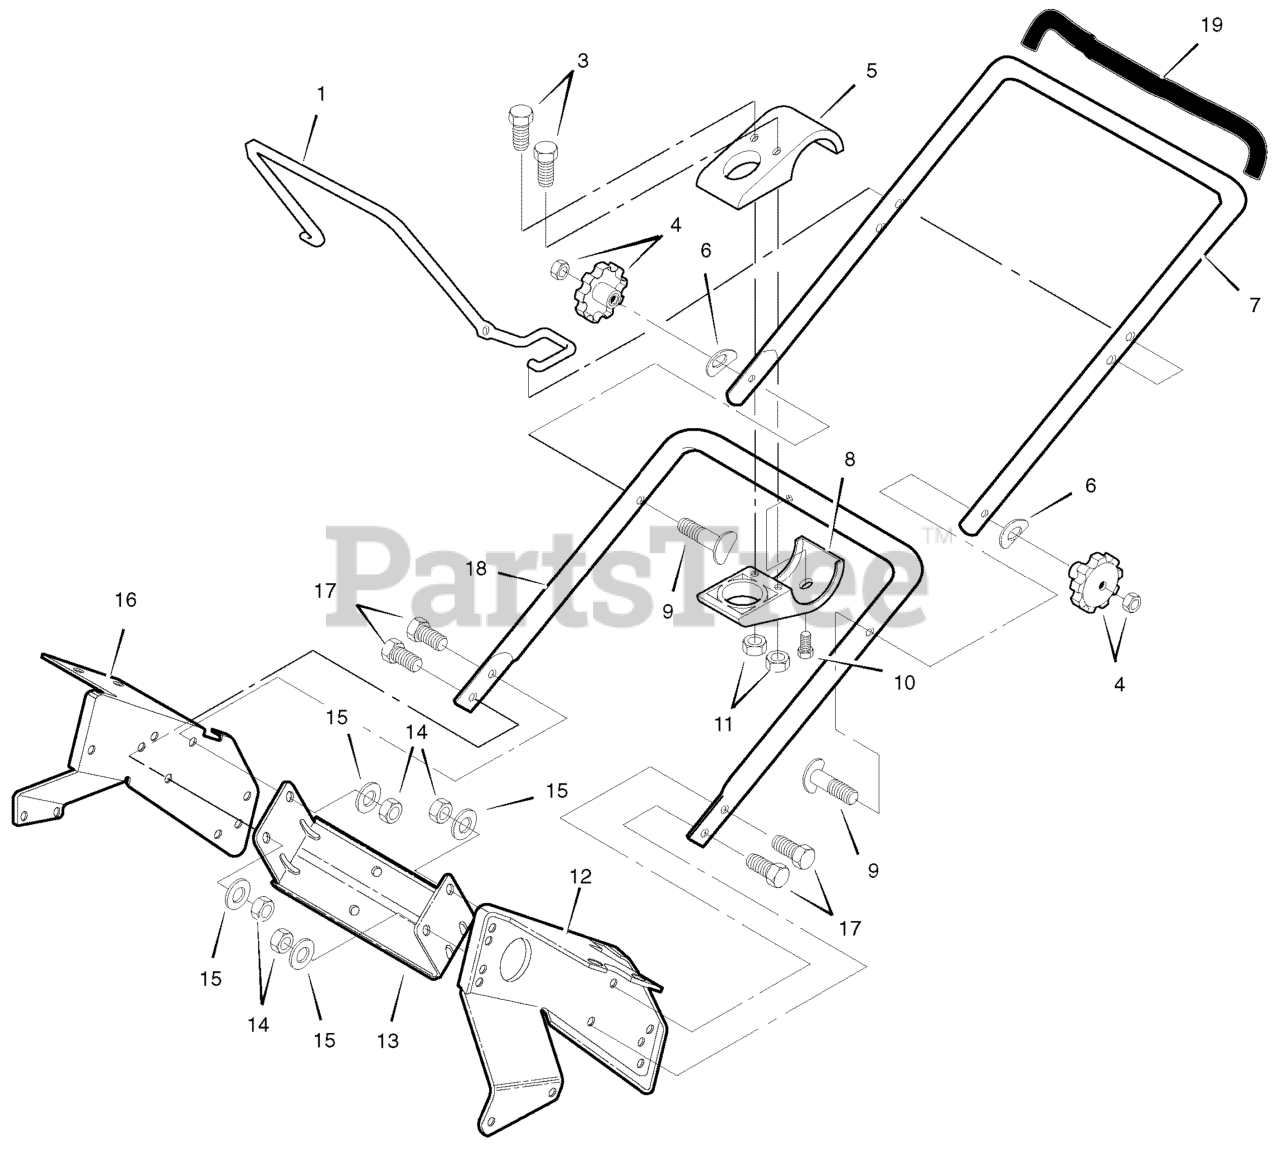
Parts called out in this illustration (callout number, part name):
1	DRIVEBAR
3	SCREW 10-24x1.00
5	BRACKET, UPPER CRANK
6	WASHER, FORMED
7	HANDLE, UPPER w/FOAM
8	BRACKET, LOWER CRANK
9	BOLT, FORMED HEAD
10	SCREW .25-20x.62
11	NUT, LOCK 10-24
12	PLATE, REAR MT LH
13	FRAME SUPPORT
14	NUT, LOCK .31-18
15	WASHER, LOCK
16	PLATE, REAR MT RH
17	SCREW .31-18x.75
18	LOWER HANDLE
19	TUBING, FOAM
